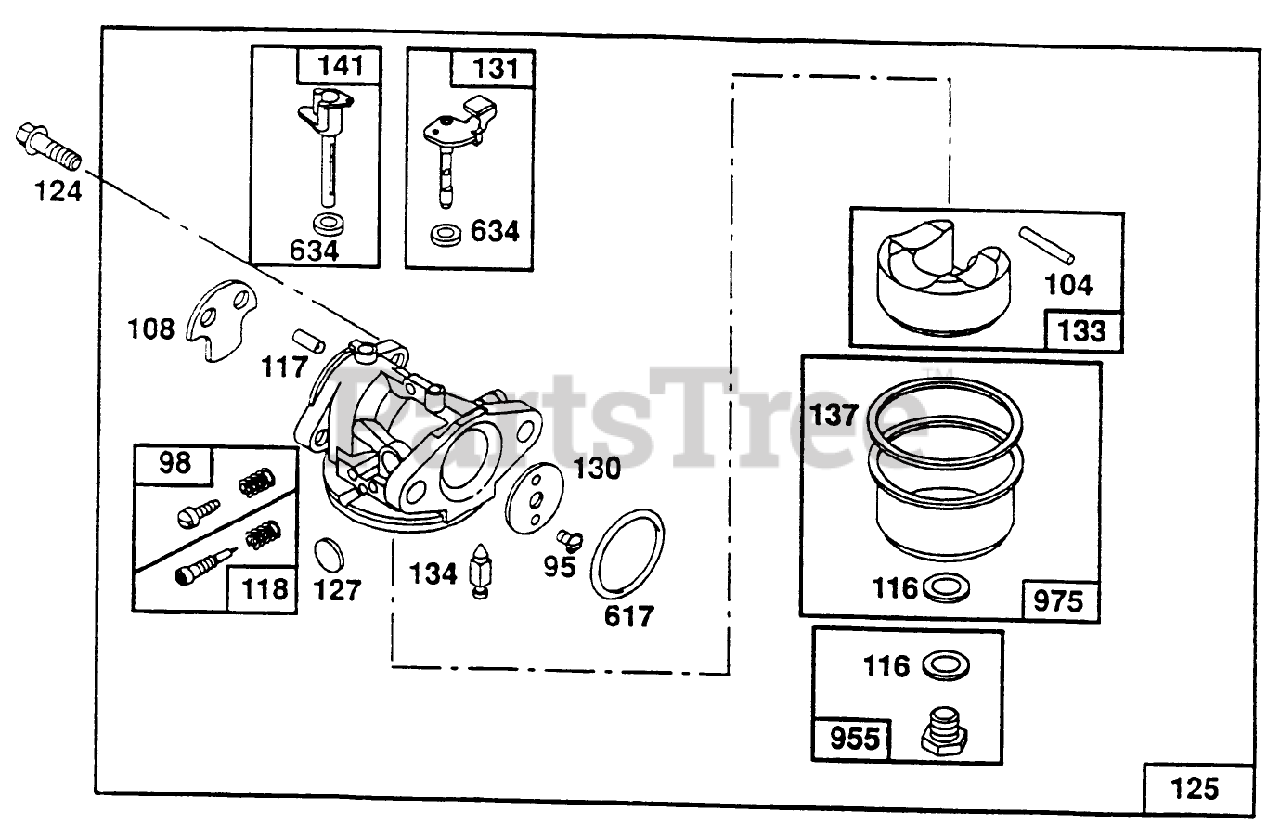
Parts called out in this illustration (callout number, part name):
95	Valve-Choke
98	Idle Speed Kit
108	Valve-Choke
116	?+ Gasket (Kit Only).
117	? Jet (Kit Only).
118	Valve-Needle
124	Screw-Hex
125	Carburetor
127	? Plug-Welch (Kit Only)
127	? Plug-Welch(Kit Only)
130	Valve-Throttle
131	Shaft and Lever
133	Float-Carburetor
134	Valve-Inlet (Includes Seat)
137	?+ Gasket (Kit Only).
141	Shaft-Choke
617	Seal-O Ring
634	?+ Washer (Kit Only).
955	Screw-Bowl Mtg.
975	Bowl-Float
